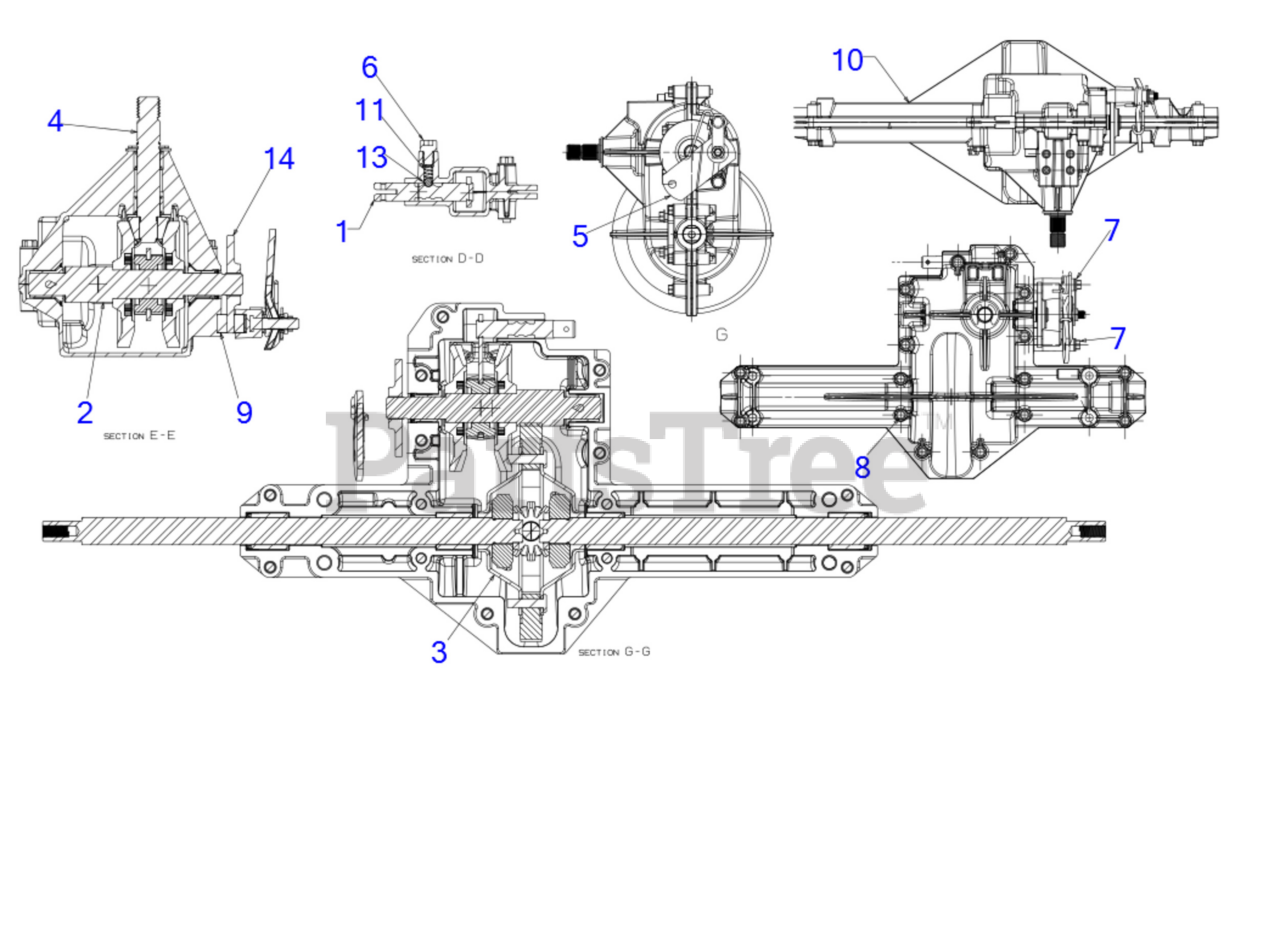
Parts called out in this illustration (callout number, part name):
1	SHAFT ASSEMBLY-DETNET
2	FWD/REV SHAFT ASSEMBLY
3	SERVICE TRANSMISSION
4	UPPER HOUSING ASSEMBLY
5	RIGHT HAND BRAKE
6	SCREW 5/16-18 x .375
7	SCREW 1/4-20 x 2.375
8	SCREW 1/4-20 X1.625
9	BRAKE PUCK
10	LOWER HOUSING
11	DETENT SHAFT SPRING
13	DETENT BALL .250
14	BRAKE DISC
